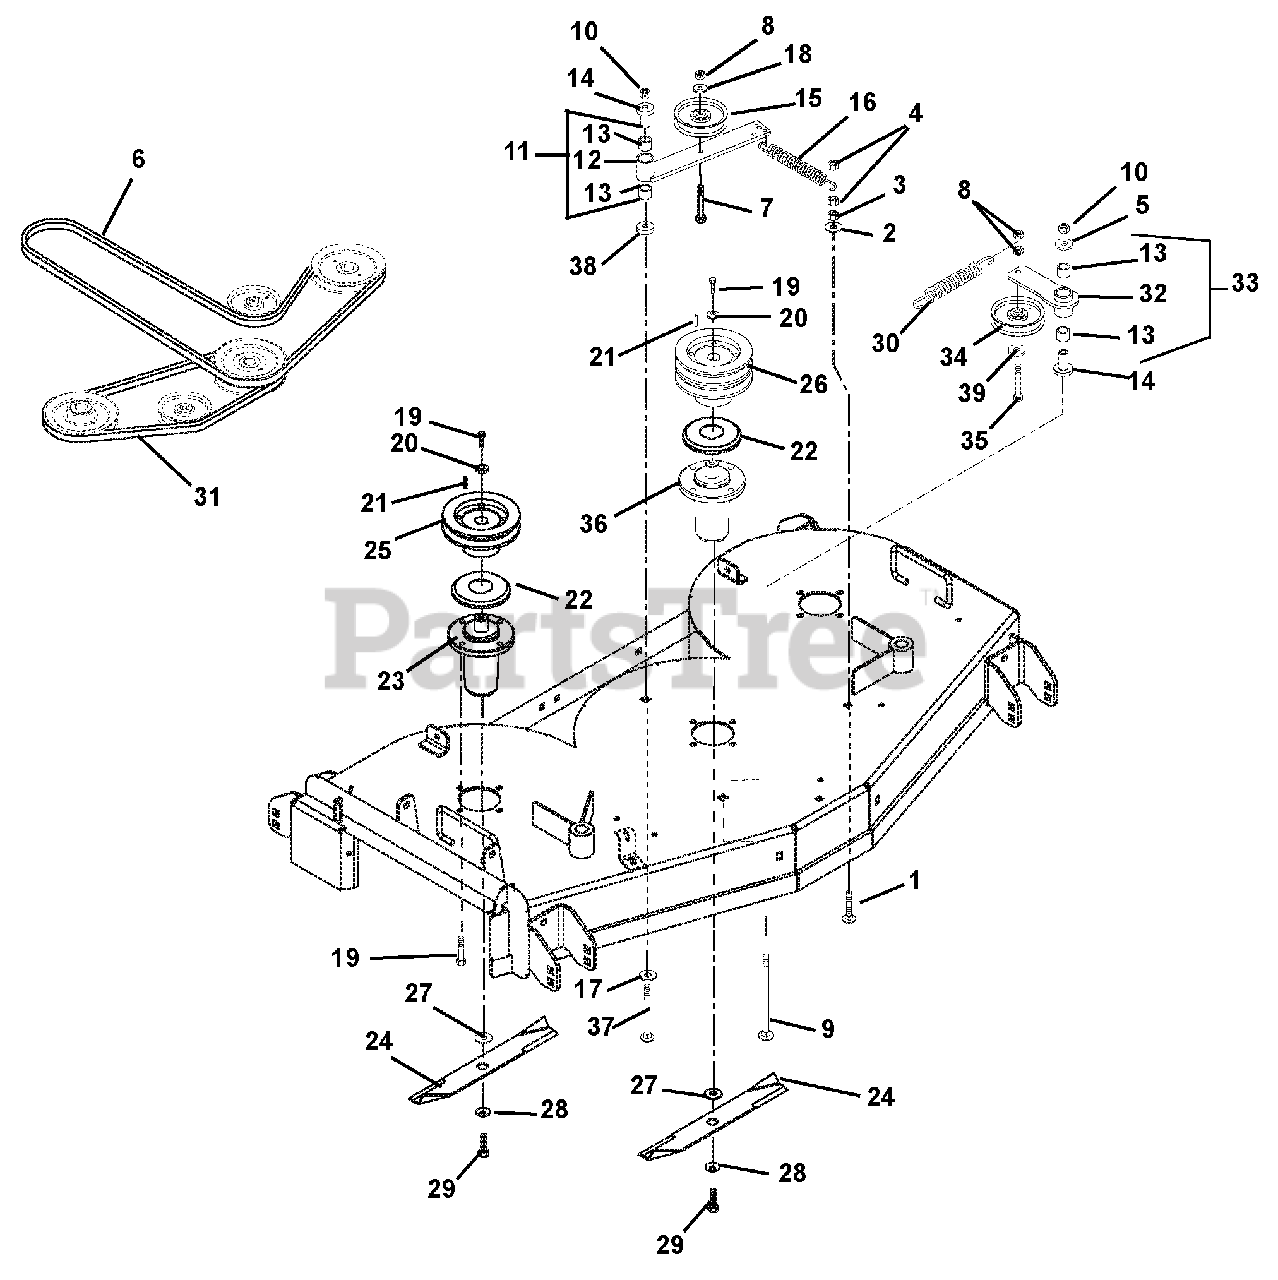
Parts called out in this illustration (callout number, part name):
1	Bolt-Round Head Square Neck .38-16 x 1.50 Grade 5
2	Washer-Locking .38 x .094 Regular
3	Nut-Hex .38-16
4	Nut-Locking-Center .38-16
5	Washer-Flat-Steel .531 x 1.25 x .10
6	V-Belt B-Section 39.38 x .65 (108, 123, 124, 125)
7	Bolt-Round Head Square Neck .38-16 x 3.00 Grade 5
8	Nut-Locking-Center .38-16
9	Bolt-Round Head Square Neck .50-13 x 3.50 Grade 5
10	Nut-Locking-Center .50-13
11	Assembly, Idler Pivot Arm (Contains Items 12 & 13)
12	Weldment, Idler Pivot Arm
13	Bearing, 1.00 x 1.12 x .75
14	Bearing, Pedestal Powdered Metal
15	Idler-Flat 4.00 x .38 (2.00 W)
16	Spring, Extension
17	Washer-Flat-Steel .755 x 1.375 x .062
18	Seal, Idler Bearing
19	Bolt-Hex .38-16 x 1.00 Grade 8
20	Washer-Flat-Steel .406 x 1.50 x .245
21	Key, Square .25 x .25 x 1.00 RC 40-50
22	Slinger-Dust
23	Assembly, Maintenance Free Spindle
24	Blade- Mower (108, 123, 124, 125)
25	Pulley
26	Sheave, Double (5.25)
27	Washer, Flat .64 x 1.81 x .250
28	Washer-Bellville .63 x 1.625 x .14
29	Bolt-Hex .62-18 x 1.75 Grade 8
30	Spring, Extension
31	V-Belt 5L-Section 49.97 x .672 (108, 123, 124, 125)
32	Arm, Idler Pivot
33	Asm, Idler Pivot Arm (Contains Items 13 and 32)
34	V-Idler, 4.00 x .38
35	Bolt-Hex .38-16 x 2.25 Grade 5
36	Spindle Assembly (Center)
37	Bolt-Round Head Square Neck .50-13 x 3.75
38	Washer-Flat-Steel .515 x 1.625 x .25
39	Washer-Flat-Steel .406 x .812 x .065
